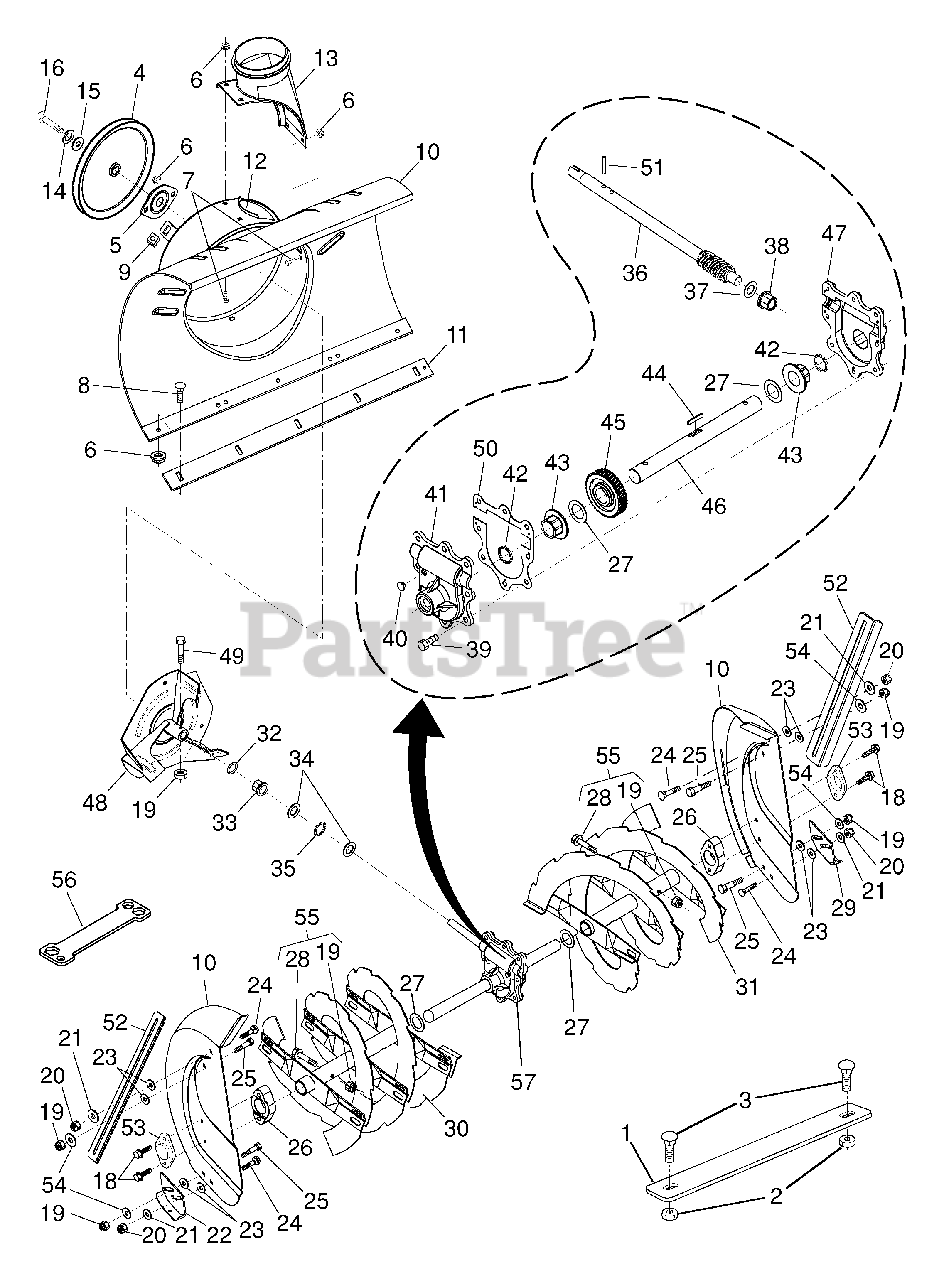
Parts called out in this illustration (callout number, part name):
1	Bar, Weight
2	Nut, Hex 5/16-18
3	Bolt, Carriage 5/16-18 x 1-1/4
4	Pulley, Impeller
5	Bearing Assembly, Flange
6	Nut, Hex Flange 5/16-18
7	Bolt, Flat Head, Carriage 5/16-18 x 5/8
8	Bolt, Carriage 5/16-1 8 x 5/8
9	Nut, Cage 3/8-16
10	Housing, Auger
11	Bar, Scraper
12	Bracket, Corner Discharge
13	Base, Discharge Chute
14	Washer, Flat
15	Washer, Lock 5/16
16	Screw, Hex Head 5/16-18 x 3/4
18	Screw, Hex Head 5/16 x 1
19	Nut, Hex Lock 1/4-20
20	Nut, Hex Lock 5/16-18
21	Washer, Flat 5/16
22	Skid Plate, RH
23	Washer, Nylon, Friction
24	Bolt, Carriage 5/16-18 x 3/4
25	Bolt, Shoulder 1/4-20
26	Bearing Retainer, Plastic
27	Washer, Thrust, 1"
28	Bolt, Shear
29	Skid Plate, LH
30	Auger Assembly, RH
31	Auger Assembly, LH
33	Bushing, Flange 3/4
34	Washer, Thrust 3/4
35	Bearing, Thrust 3/4
36	Shaft, Impeller
37	Washer, Thrust 5/8
38	Bushing, Flange 5/8
39	Screw, Hex Head 5/16-18 x 3/4
40	Plug, Case
41	Housing, Gearbox, RH
43	Bushing, Flange, 1"
44	Key, Square 1/4 x 1/4 x 7/8
45	Gear, Worm
46	Shaft, Auger
47	Housing, Gearbox, LH
48	Impeller Assembly
49	Screw, Hex Head 1/4-20 x 1-5/8
50	Gasket, Gearbox
51	Pin, Roll 3/16 x 1-1/8
52	Bar, Drift
53	Bearing, Auger
54	Washer, Flat 1/4
55	Kit, Shear
56	Multi-Wrench
57	Gearbox Assembly
